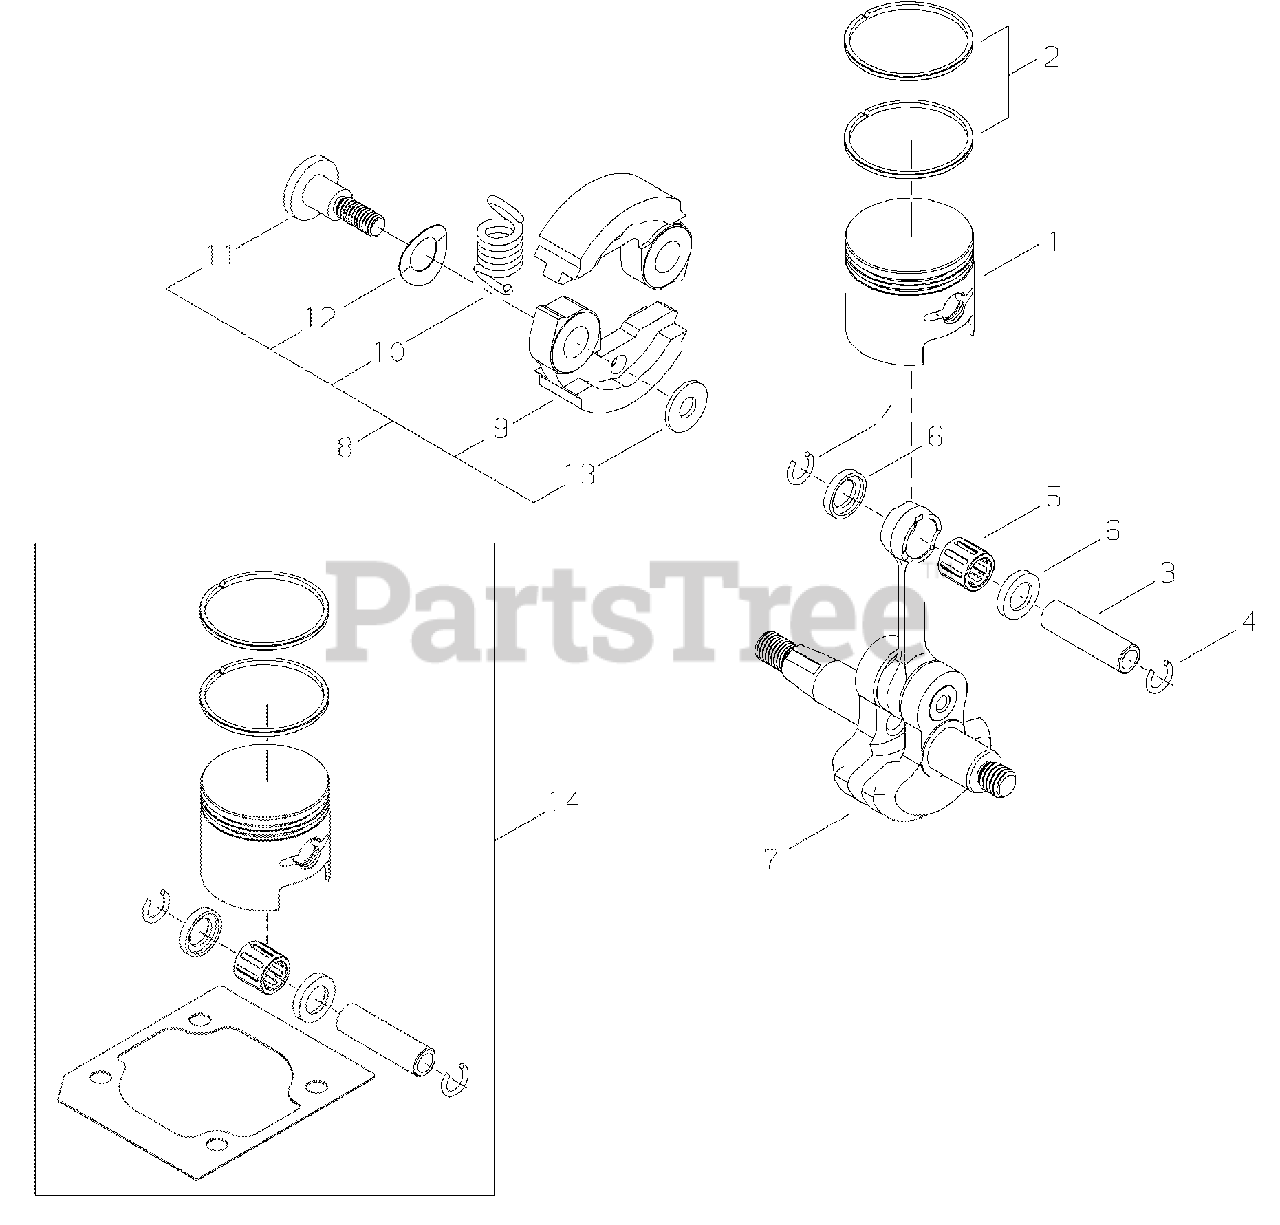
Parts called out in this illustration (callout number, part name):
1	PISTON
2	RING, PISTON
3	PIN, PISTON 8
4	RING, SNAP
5	BEARING, NEEDLE 8
6	WASHER, THRUST 8
7	CRANKSHAFT ASSY
8	CLUTCH ASSY
9	SHOE, CLUTCH
10	SPRING, CLUTCH
11	BOLT, CLUTCH
12	WASHER, SPRING
13	WASHER 6 MM
14	PISTON KIT
